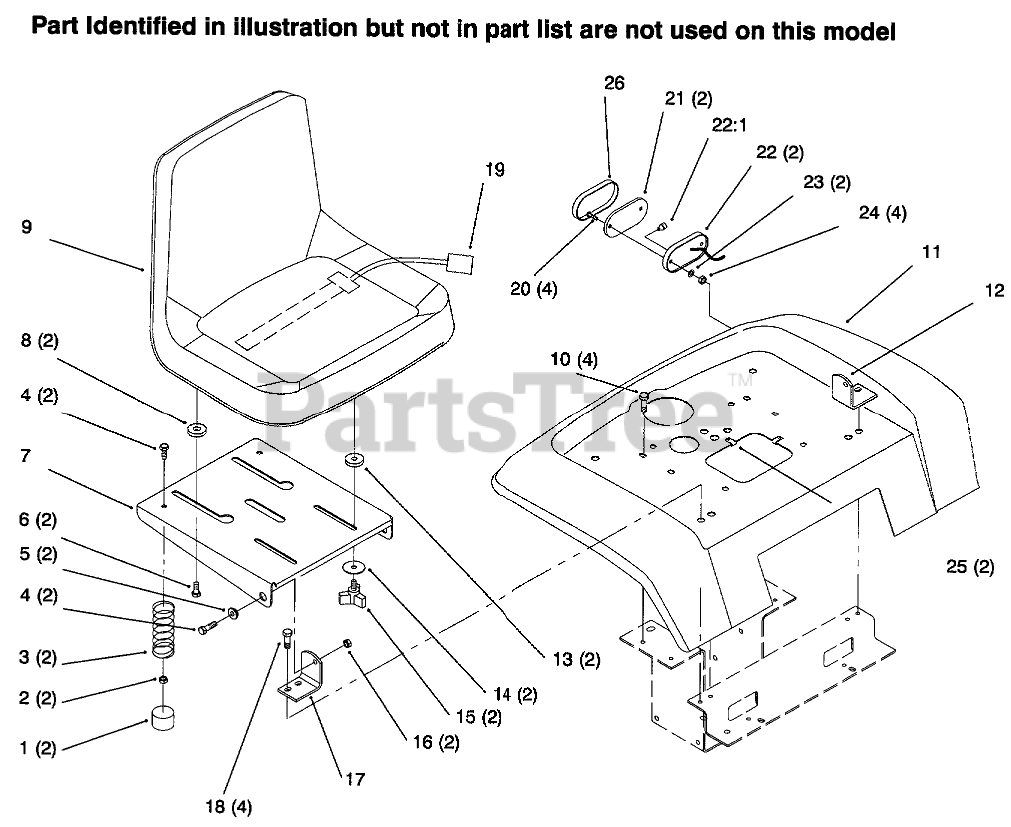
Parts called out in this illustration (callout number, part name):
1	CAP-PROTECTOR
2	NUT-LOCK, NI
3	SPRING-COMPRESSION
4	SCREW-HH
5	BUSHING
6	BOLT-SHOULDER
7	SUPPORT - SEAT (BLACK)
8	SPACER-NYLON
9	SEAT-V-511
10	Bolt
12	BRACKET-PIVOT, LH
13	SPACER-NYLON
14	WASHER
16	NUT-LOCK, NI
17	BRACKET-PIVOT, RH
18	SCREW-HWHTF
19	SWITCH-SEAT
20	SCREW-PPH
22	BASE-TAIL LIGHT
23	WASHER-LOCK, INT
24	NUT-LOCK, NI
25	SPEED CLIP
26	LENS-TAIL LIGHT
28	Decal-Rear Fender
29	DecaI-Ce
